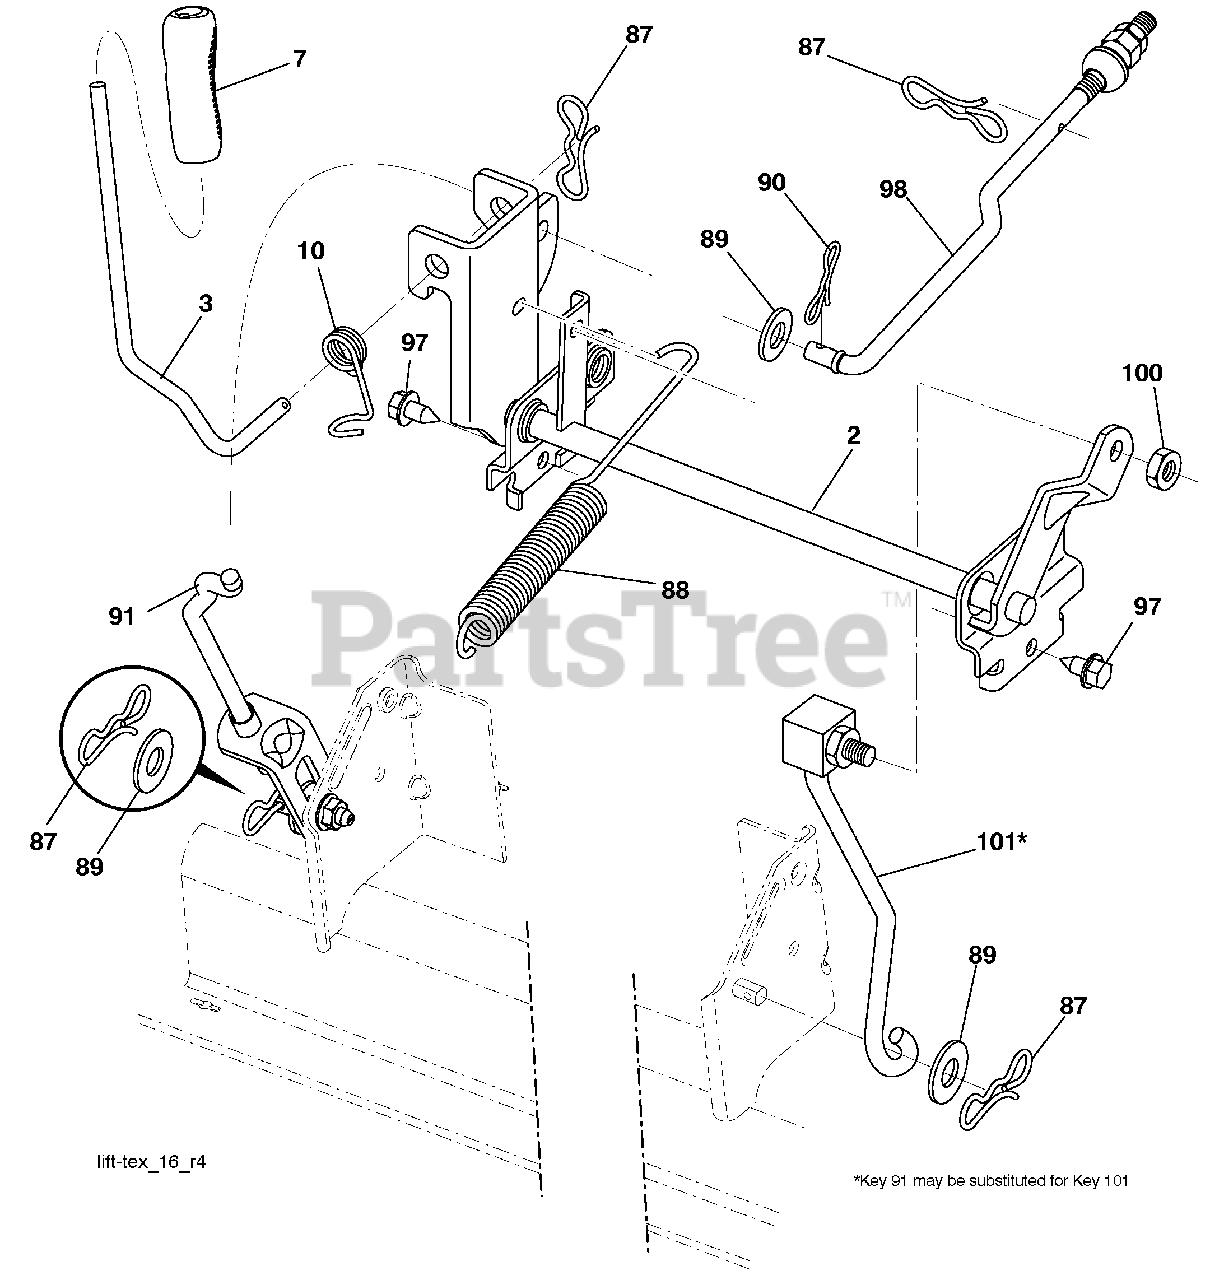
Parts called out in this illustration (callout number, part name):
2	Shaft Asm., Lift
3	Lever Asm., Lift Rh
7	Grip, Lever
10	Spring Torsion
87	Pin Cotter 7/16 Bow Tie Lock
88	Spring Lift Assist
89	Washer Clear Zinc
90	Pin Cotter 5/16 Bow Tie Lock
91	Link Lift Susp Mower Rear
97	Screw 3/8-16 X .75
98	Link Lift Susp. Front Mower
100	Nut Center Lock 3/8-16 Unc
101	Link Asm. Lift Fxd
